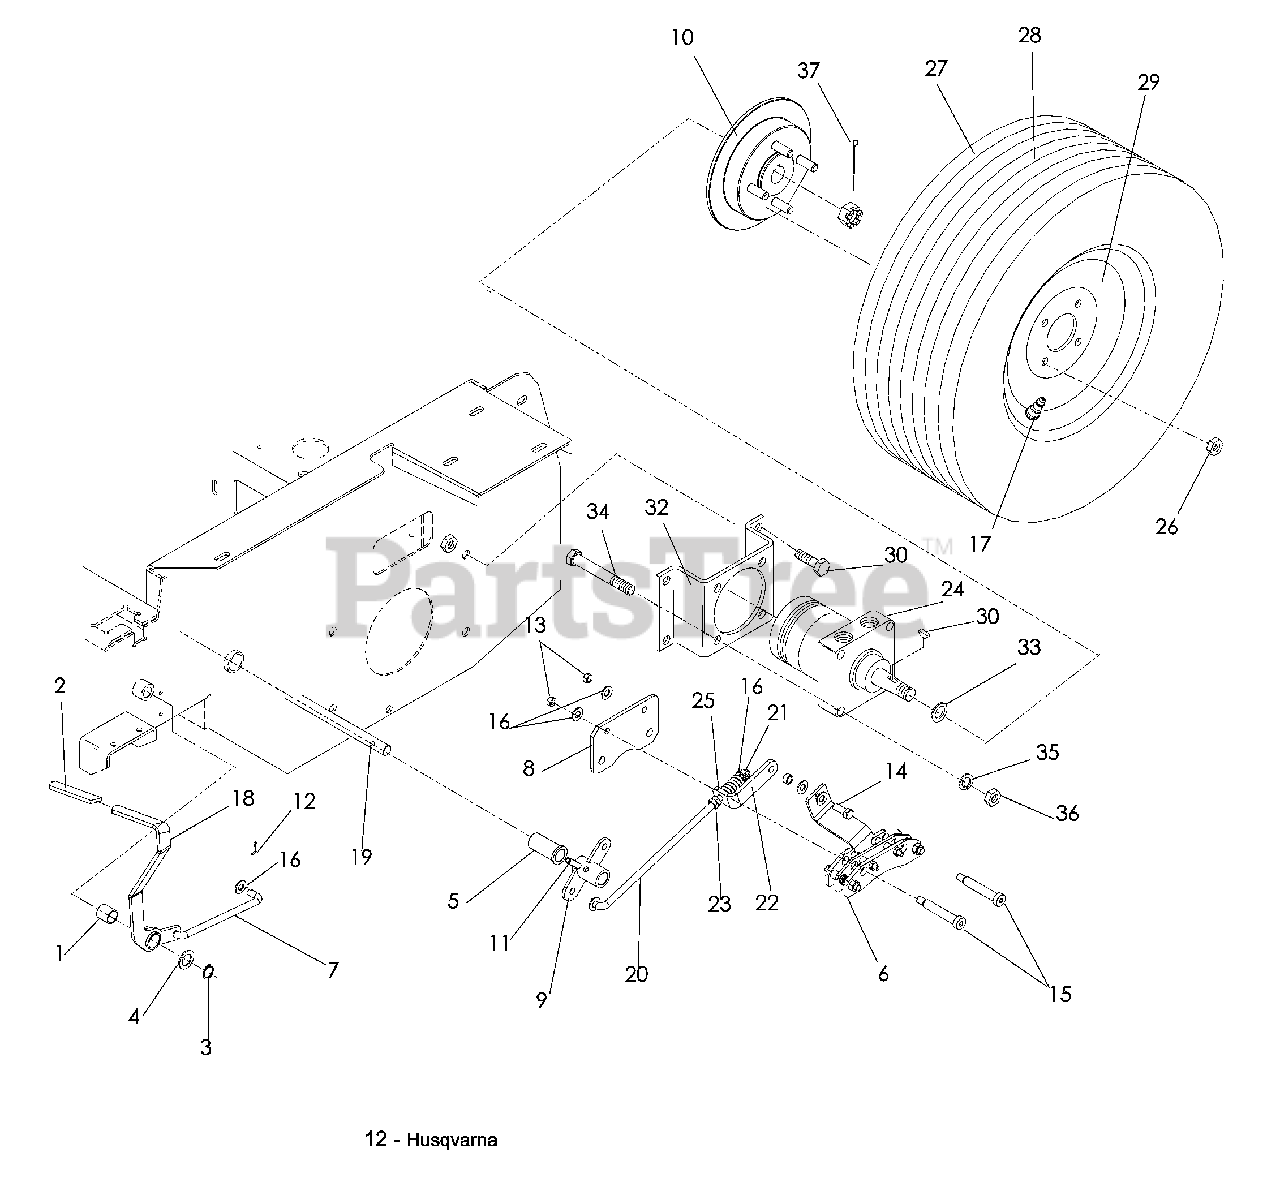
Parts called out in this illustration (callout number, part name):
3	RING, RETAINING 7/8
4	BUSHING, MACHINE
5	BUSHING, POLYMER ¾ x
7	LINKAGE, BRAKE
8	PLATE, BRAKE
9	BELLCRANK, BRAKE
11	PIN, ROLL, 5/16" DIA.
12	PIN, COTTER 3/32 x ¾
13	NUT 3/8-16 JAM NYLOC
14	HCS 3/8-16 x 1
15	SB 3/8-16 x 2½ SKT HD
16	WASHER 3/8 SAE FLT
17	VALVE STEM
18	BRAKE LEVER
19	SHAFT, CROSS
20	LINKAGE, REAR BRAKE
21	NUT 3/8-24 CENTERLOCK
22	BRACKET, L
23	NUT 3/8-24 JAM
24	WHEEL MOTOR, TJ
26	NUT ½-20 HEX LUG
27	TIRE, COMPLETE
28	TIRE, 23 x 9.5-12
29	RIM, OFFSET 1"
30	KEY, WOODRUFF
31	NUT ½-13 HEX NYLOC
32	STANDOFF, WHEEL MOTOR
33	BUSHING, MACHINE, 1"
34	HCS ½-13 x 2¾
35	LOCKWASHER ½
36	NUT ½-13 HEX
37	PIN, COTTER
